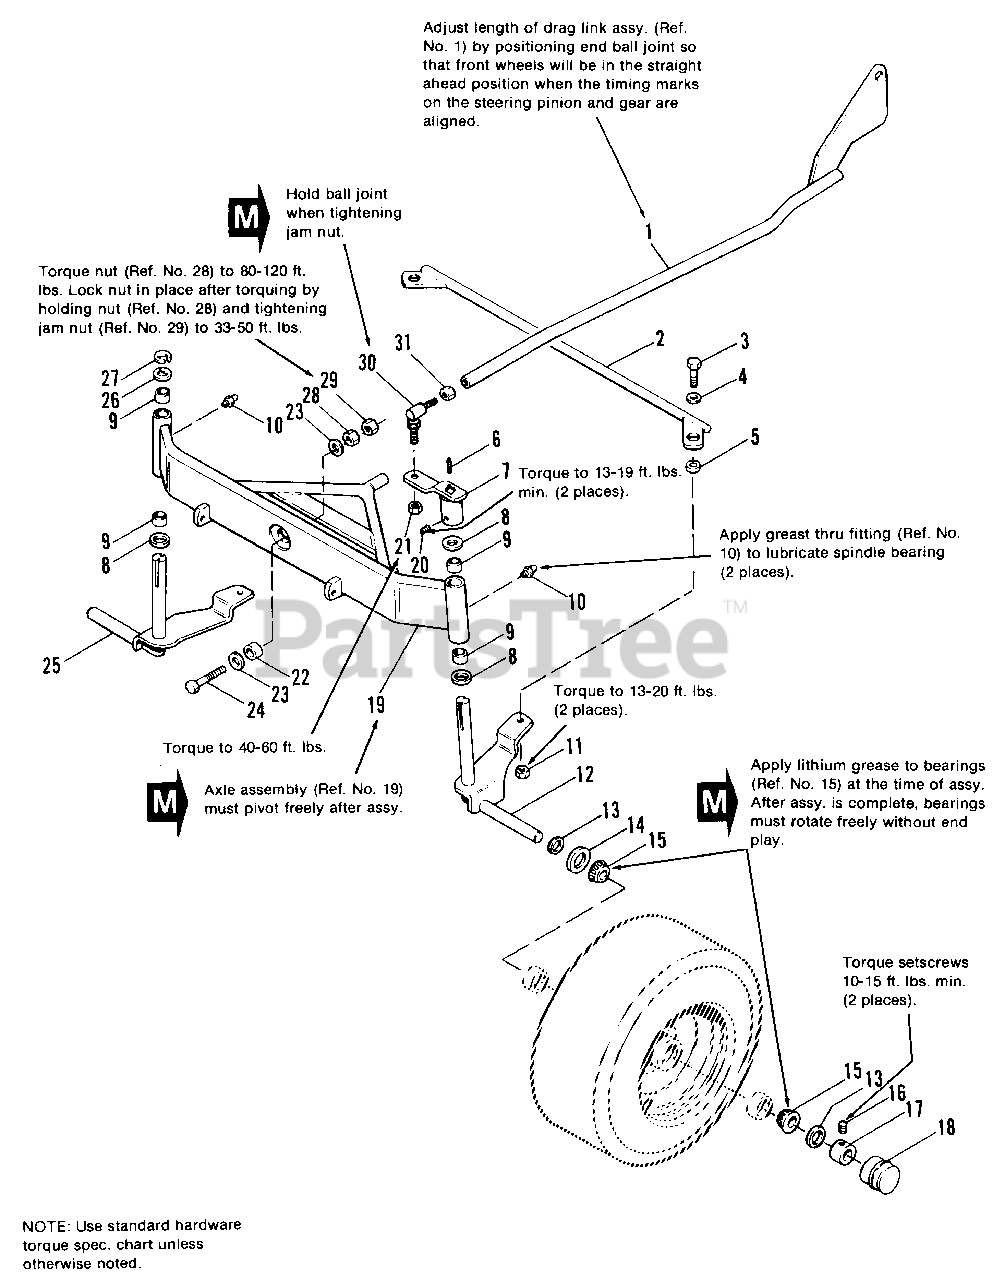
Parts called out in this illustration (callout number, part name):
1	LINK ASSY., Drag
2	ROD ASSY., Tie
3	CAPSCREW. Hex Hd., 3/8-16 x 1
4	WASHER, Plain, 3/8
6	KEY, Square
7	ARM ASSY., Steering
10	FITTING, Grease
11	LOCKNUT, Hex, 3/8-16
12	SPINDLE ASSY., LH
15	CONE, Bearing
16	SETSCREW, 5/16-18 x 5/16
17	COLLAR, Set
18	CAP, Hub
19	AXLE ASSY., Front
20	SETSCREW, 5/16-18 x 1/2
21	LOCKNUT, Hex, 1/2-20
23	WASHER, Plain, 1/2
24	CAPSCREW, Hex Hd., 1/2-13 x 2-1/4
25	SPINDLE ASSY., RH
27	RING, Retaining
28	LOCKNUT, Hex, 1/2-13
29	LOCKNUT, Hex, Jam, 1/2-13
30	BALL, Joint
31	LOCKNUT, Hex, Jam, 1/2-20
